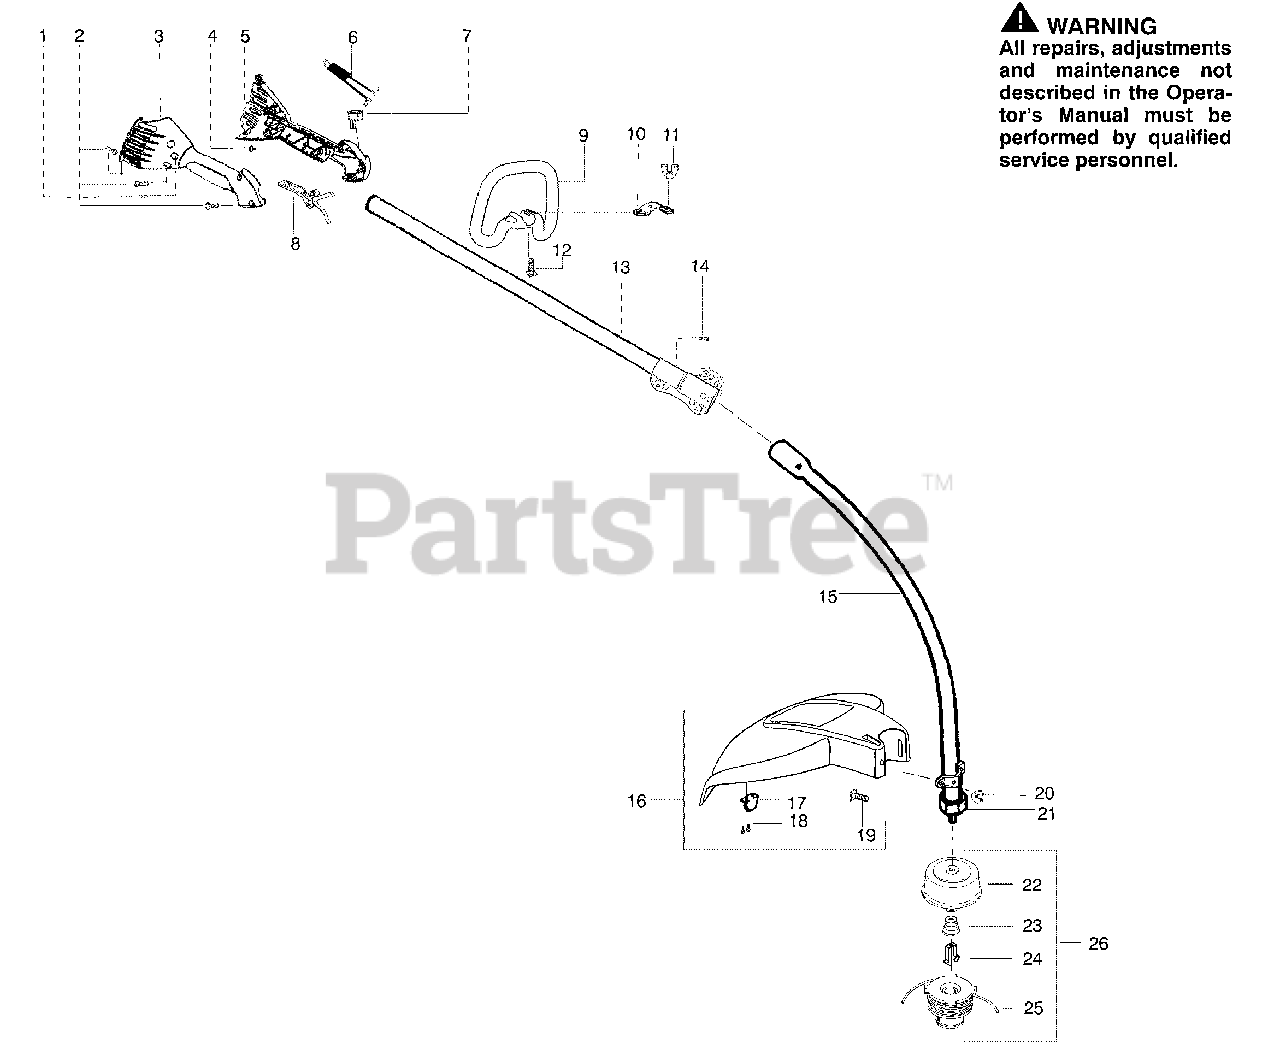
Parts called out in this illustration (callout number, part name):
1	Screw-alignment
3	Hsg.-Throttle right
4	Screw-Cable Retention
5	Hsg.-Left throttle
6	Assy-Wire
7	Kit-Switch
8	Trigger-Throttle
9	Handle-Assist
10	Clamp-Assist Handle
11	Wingnut
13	Assy-Upper Shaft
15	Assy-Lower Shaft
16	Kit-Shield Assy.
17	Limiter-Line
20	Wingnut
22	Assy-Hub/Arbor
23	Spring-Return
24	Retainer-Spool
25	Accy-Wound Spool
26	Accy-Cutting Head
